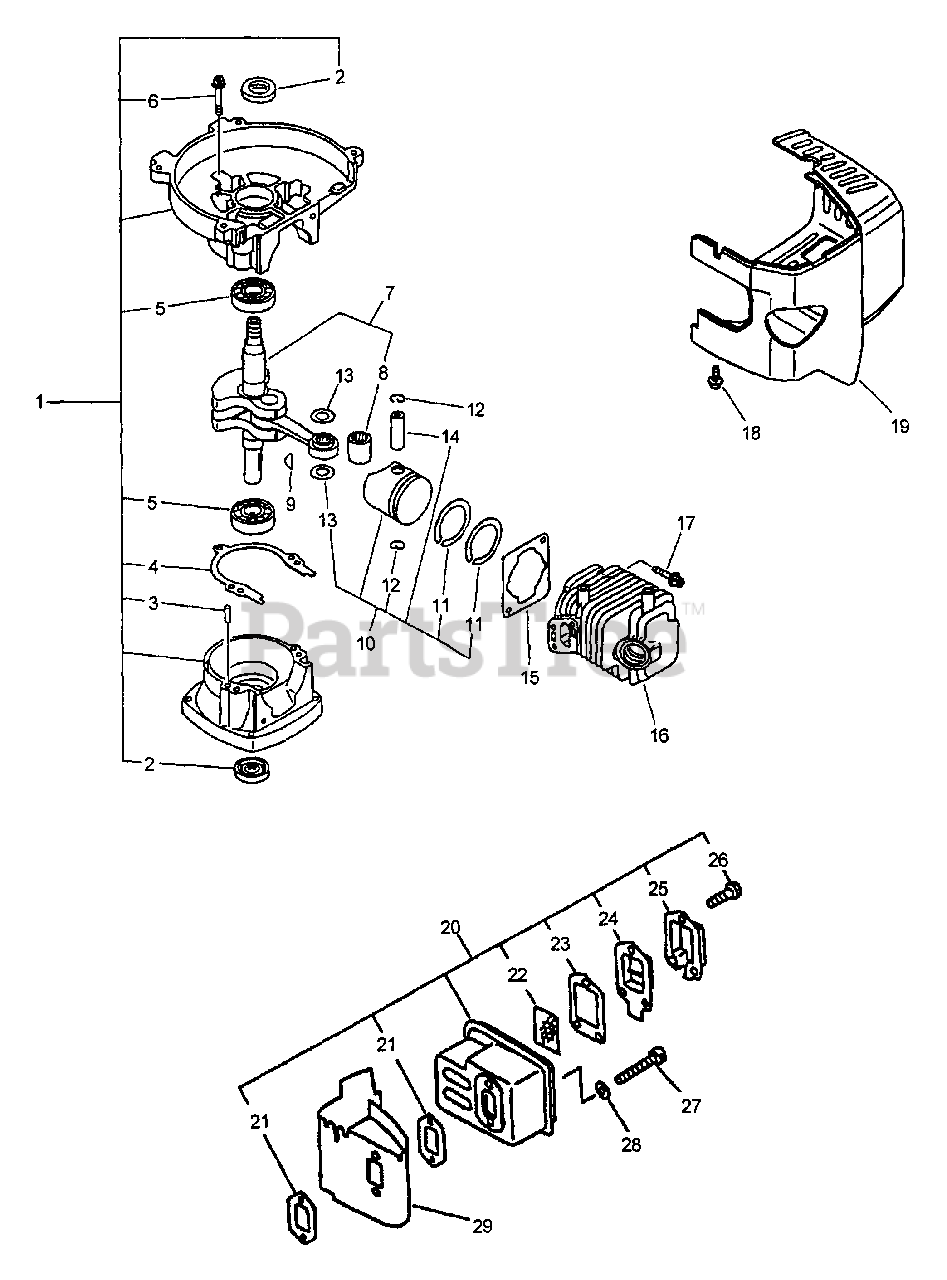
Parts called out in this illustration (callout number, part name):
1	CRANKCASE KIT
2	SEAL, OIL
3	PIN - LOCATING
4	GASKET, CRANKCASE
5	BEARING, BALL - 6201
6	SCREW - 5X28
7	CRANKSHAFT ASSY
8	BEARING, NEEDLE
10	PISTON KIT
11	RING, PISTON
12	RING, RETAINING
13	SPACER, PISTON
14	PIN, PISTON
15	GASKET, CYLINDER
16	CYLINDER
17	SCREW - 5X22
18	SCREW - 4X18
19	COVER, ENGINE - GRAY
20	MUFFLER ASSY
21	GASKET, EXHAUST
22	SCREEN, SPARK ARRESTOR
23	GASKET, EXHAUST
24	GASKET, EXHAUST - INNER
25	GUIDE, EXHAUST - OUTER
26	SCREW - 4X10
27	SCREW - 5X50
28	WASHER - 5
29	SHIELD, EXHAUST
